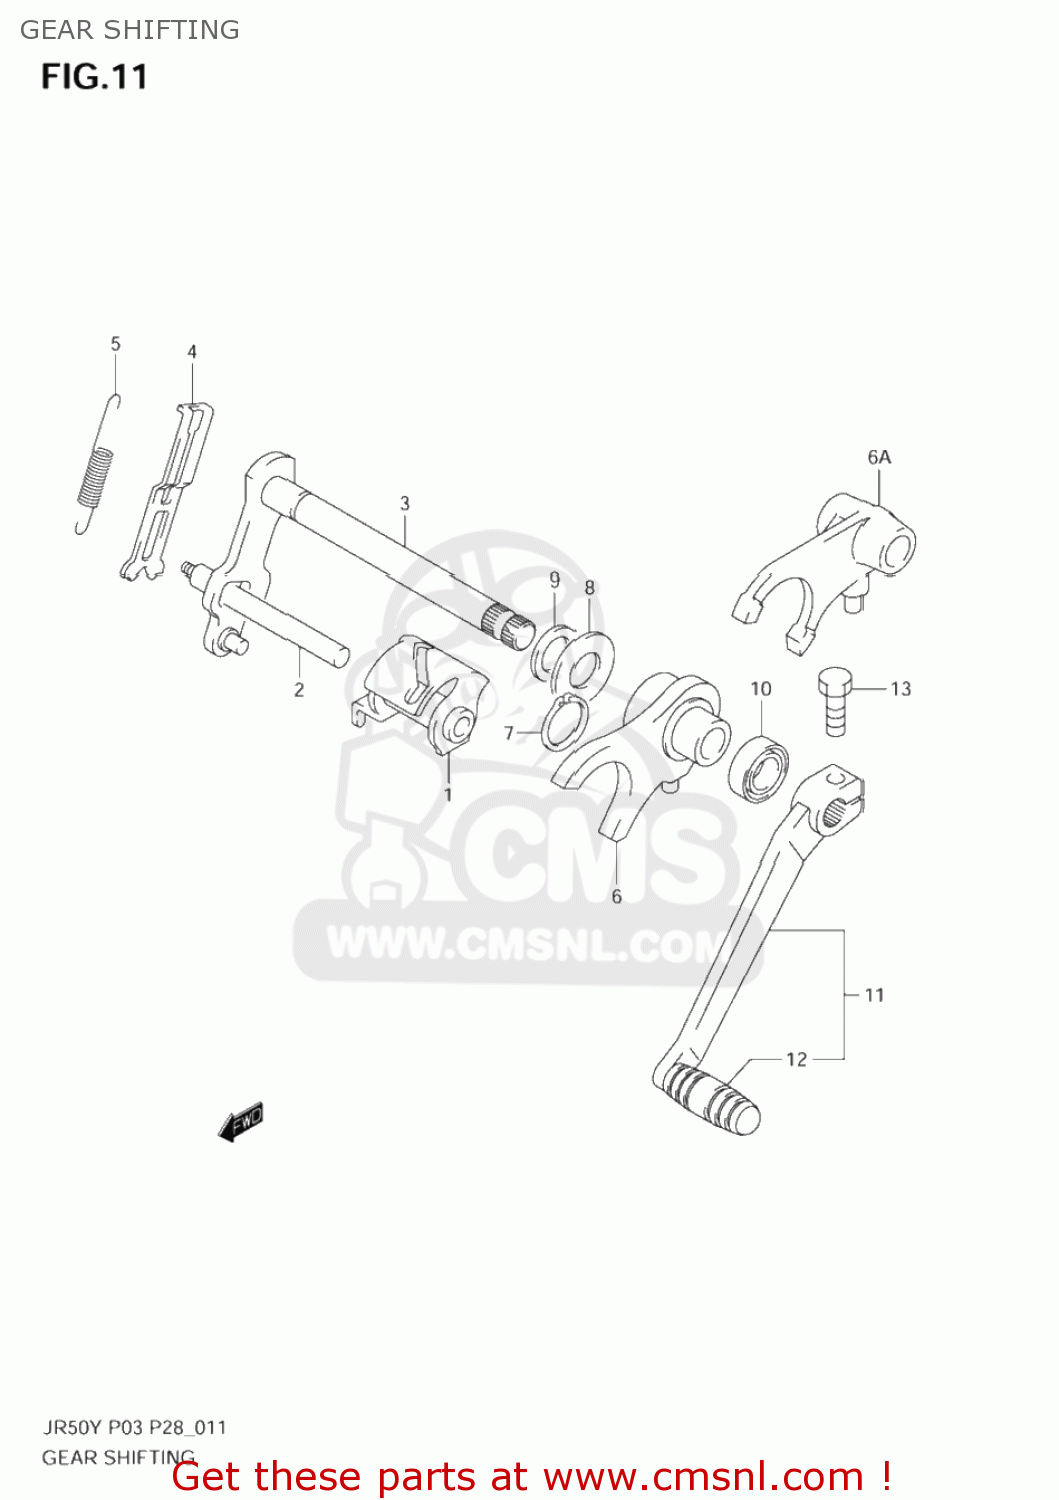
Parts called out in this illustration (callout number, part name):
1	CAM,GEAR SHIFT
2	SHAFT,GEAR SHIFT CAM
3	SHAFT,GEAR SHIFT
4	ARM,GEAR SHIFT CAM STOPPER
5	SPRING
6	FORK,GEAR SHIFT NO.1
6A	FORK,GEAR SHIFT
7	CIRCLIP,12 MM
8	WASHER
9	WASHER
10	OIL SEAL
11	LEVER ASSY,GEAR SHIFT
12	RUBBER,GEAR SHIFT PEDAL
13	BOLT
